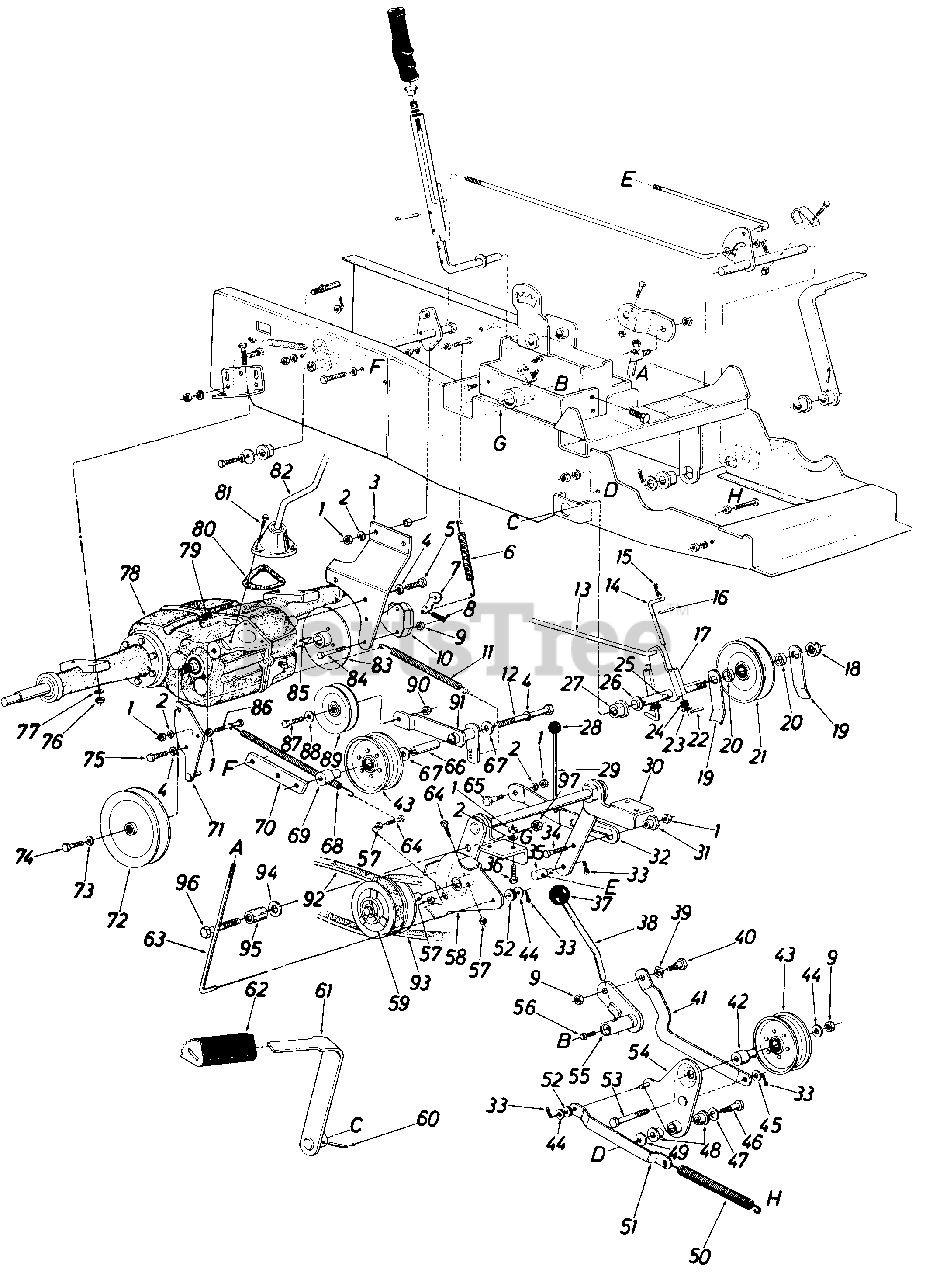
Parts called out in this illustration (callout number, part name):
1	Hex Nut 5/16-18 Thd.
2	L-Wash. 5/16" Scr.*
3	Transaxle Support Brkt.
4	L-Wash. 3/8" Scr.*
5	Hex Scr. 3/8-16 x 1.00" Lg. (Grade 5)
6	Brake Spring
7	Cam Lever
8	Brake Return Spring
9	Hex Top L-Nut 3/8-16 Thd.
10	Disc Brake Ass'y. Comp.
11	Brake Spring
12	Hex Scr. 3/8-16 x 4.50" Lg.
13	Brake Rod Ass'y.
14	Belt Guard
15	Hairpin Cotter 5/16" Dia.
16	Roll Pin 1/8" Dia. x .63" Lg. *
17	Brake Control Brkt. Ass'y.
18	Hex Nut 5/8-18 Thd.
19	Belt Guide
20	Spacer 5/8 I.D. x 7/8 O.D. x .25" Lg.
21	V-Idler Pulley 4-1/2" O.D.
22	Roll Pin 1/8" Dia. x .63" Lg.*
23	Flat Wash.
24	Spring
25	Roll Pin 3/16" Dia. x 1.50" Lg. *
26	Fl-Wash. .76 I.D. x .06
27	Flange Bearing-Plastic
28	Parking Brake Knob
29	Parking Brake Rod
30	Mount Ass'y.
31	Shoulder Nut
32	Parking Brake Brkt.
33	Cotter Pin 1/8" Dia. x .75" Lg.*
34	Hex Scr. 5/16-18 x 1.00 Lg.*
35	Ferrule
36	Hex Sems Scr. 5/16-18 x .75" Lg.
37	Ball Knob
38	PTO Handle
39	Wave Wash. 1/2" Dia.
40	Shoulder Bolt
41	Clutch Idler Link
42	Idler Adapter
43	Flat Idler Pulley 4-5/8" Dia.
44	Fl-Wash. 3/8" I.D.*
45	Fl-Wash. 1/2" I.D. x 3/4" O.D. *
46	Shoulder Scr.
47	Fl-Wash. 1/2" I.D.
48	Bronze Bearing
49	Bell-Wash.
50	Extension Spring
51	Spring Strap
52	Rubber Washer
53	Hex Scr. 3/8-16 x 2.00" Lg.*
54	Clutch Idler Plate
55	Actuator Lever Ass'y.
56	Hex Hd. Self-Tap Scr. 1/4-20 x.50" Lg.*
57	Hex Cent. L-Nut 1/4-28 Thd.
58	Variable Speed Belt Guard Ass'y.
59	Variable Speed Pulley
60	Spring Pin Spiral 1/4" Dia. x 1.50" Lg.
63	Control Rod
64	Hex Scr. 1/4-28 x 1.25" Lg. (Grade 5)
65	Shoulder Scr.
66	Spacer Tube
67	Fl-Wash. 3/8" I.D. x 1.00" O.D. *
68	Extension Spring
69	Idler Adapter
70	Idler Bracket
71	Spring Brkt. Ass'y.
72	Transaxle Pulley 7.00" Dia.
73	Belleville Wash.
74	Hex Scr. 3/8-24 x .75" Lg.*
75	Hex Scr. 3/8-16 x 1.00" Lg.*
76	Hex Nut 3/8-16 Thd.*
77	L-Wash. 5/8" Scr. Heavy Duty
78	Transaxle
79	Bumper
80	Part of Transaxle
81	Part of Transaxle
82	Part of Transaxle
83	Brake Disc Ass'y.
84	Hex Scr. 3/8-16 x 2.50" Lg.*
85	Hi-Pro Key 1/8" x 1.06" Lg.
86	Hex Scr. 5/16-18 x 2.25" Lg.*
87	Hex Scr. 3/8-16 x 1.50" Lg.*
88	Fl-Wash. 3/8" I.D.*
89	4" Dia. V-Idler
90	Hex Cent. L-Nut 3/8-16 Thd. *
91	Idler Arm Ass'y.
92	V-Belt 5/8 x 45" Lg.
93	V-Belt 5/8 x 63" Lg.
94	Bell-Wash. 3/8 I.D.
95	Sleeve
96	Hex Bolt 3/8-16 x 2.50" Lg.*
97	Hex Nut 3/8-16 Thd.
